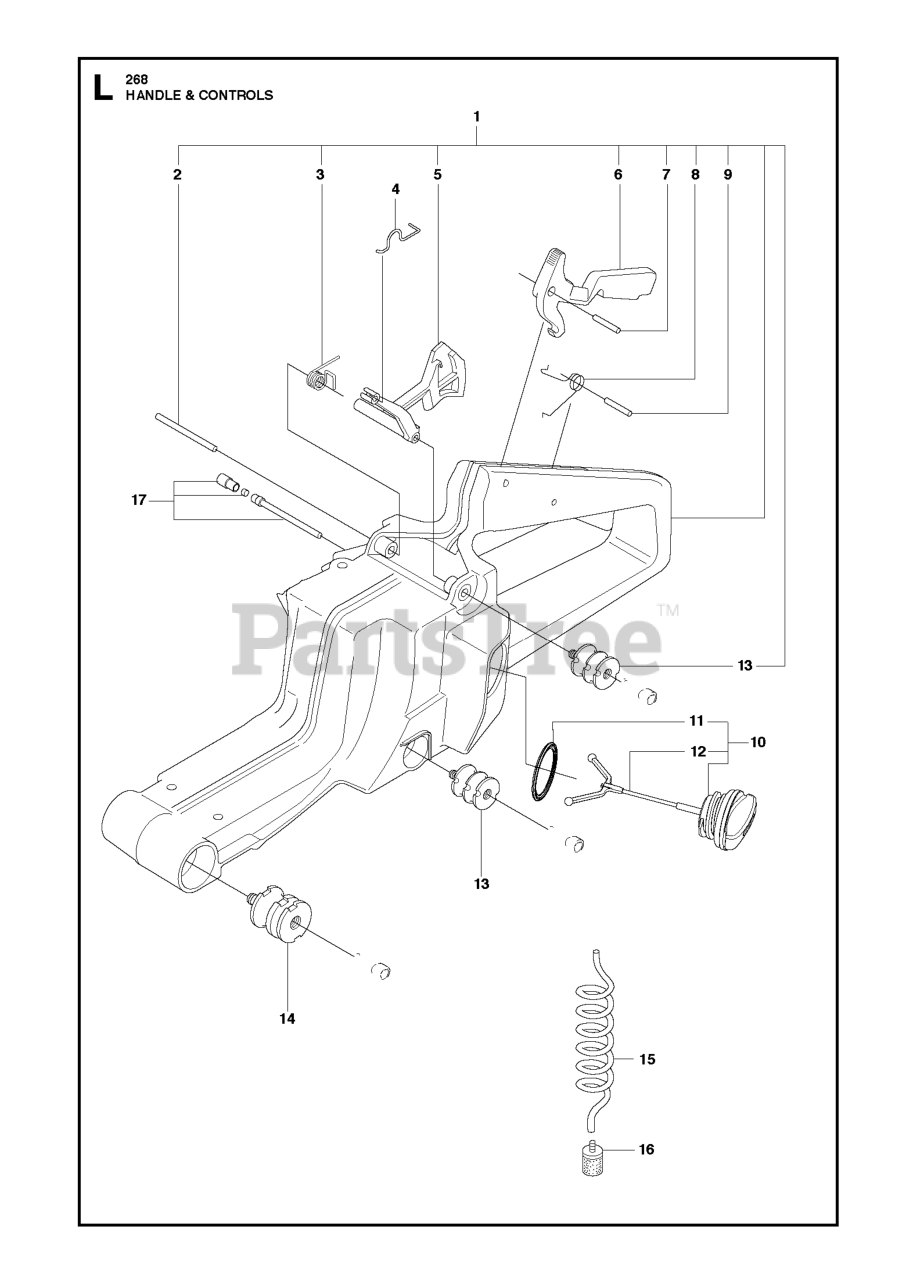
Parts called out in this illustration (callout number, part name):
1	TANK UNIT CPL
4	THROTTLE ROD
6	THROTTLE CATCH
7	SPRING PIN 3X24
9	SPRING PIN 3X24
13	ANTIVIBE ELEMENT
14	ANTIVIBE ELEMENT
15	FUEL HOSE
16	RP FUEL FILTER
